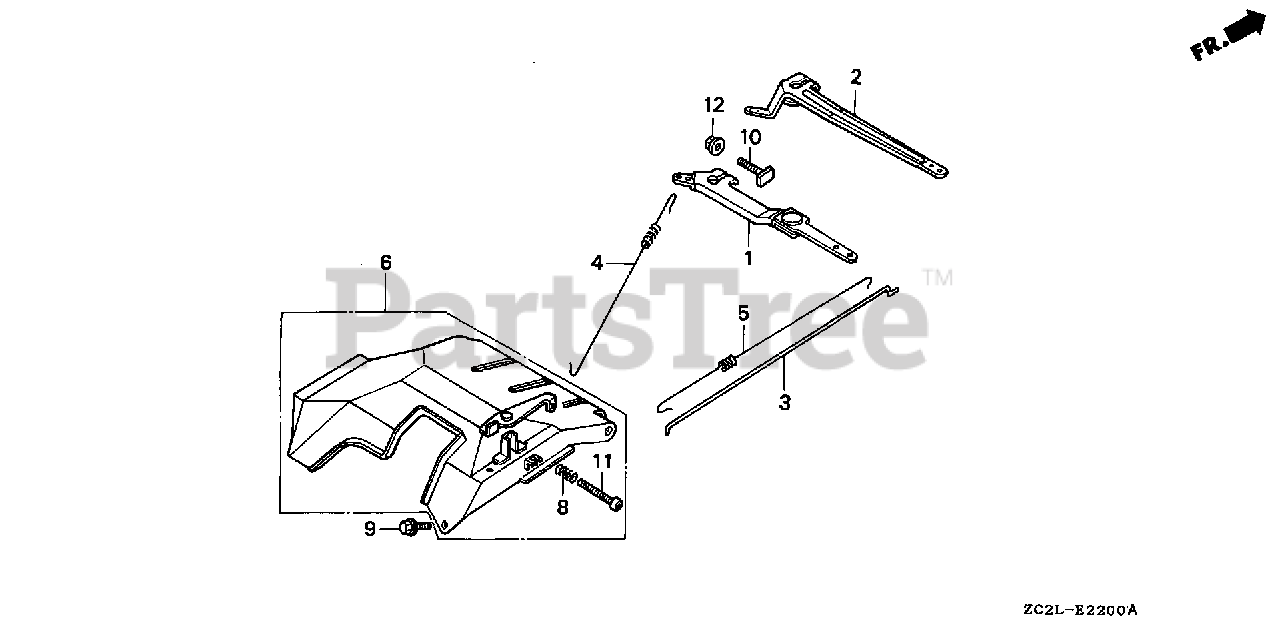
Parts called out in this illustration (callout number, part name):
1	ARM, GOVERNOR
3	ROD, GOVERNOR
4	SPRING, GOVERNOR (L=137.5MM)
5	SPRING, THROTTLE RETURN
6	CONTROL ASSY.
8	SPRING, CONTROL ADJUSTING
9	BOLT, FLANGE (6X12) (CT200)
10	BOLT, GOVERNOR ARM
11	SCREW, PAN (5X35)
12	NUT, FLANGE (6MM)
